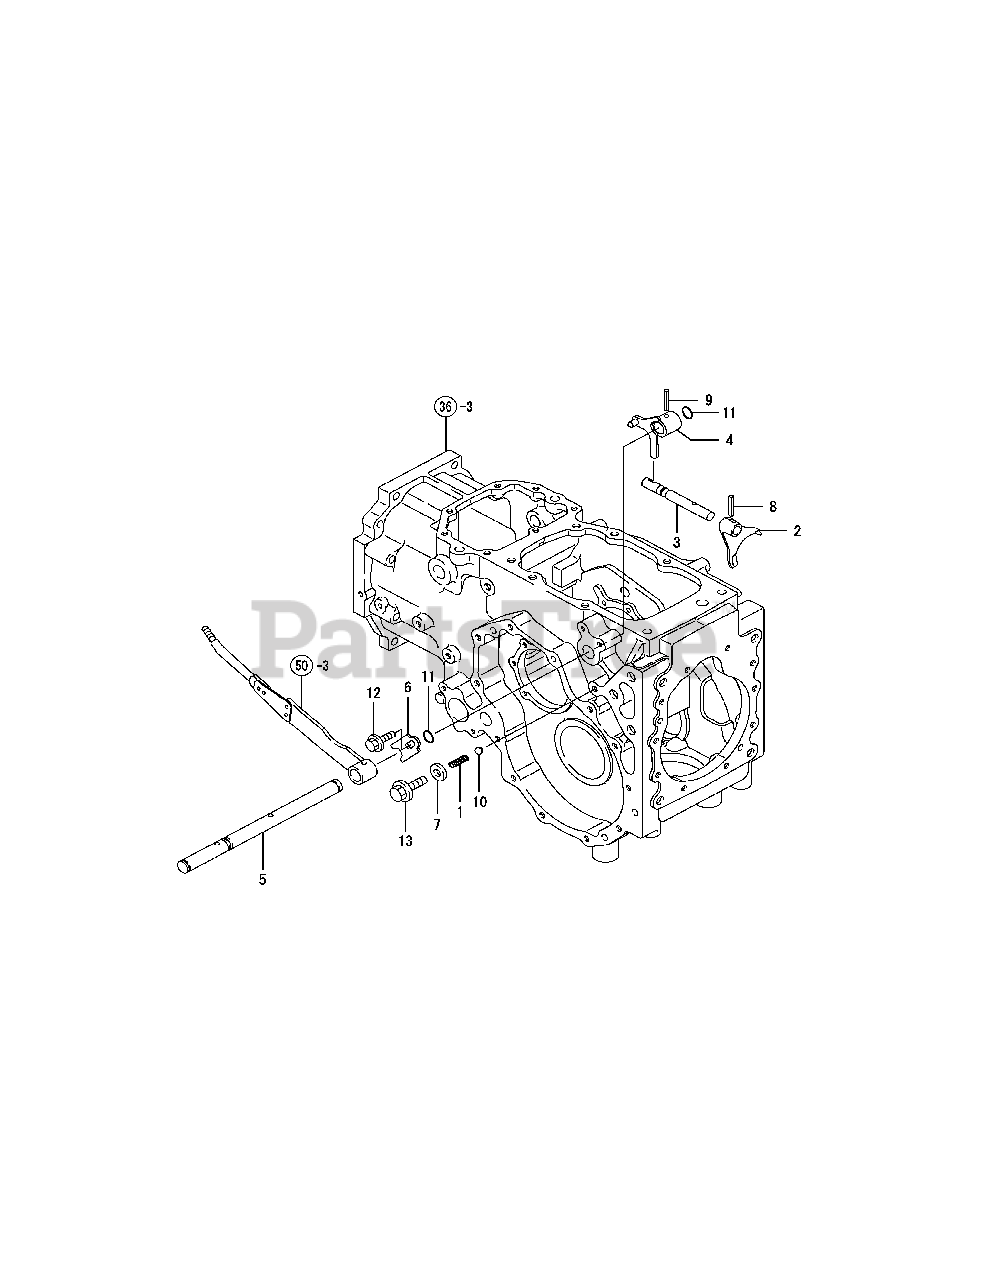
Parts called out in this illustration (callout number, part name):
2	FORK, SHIFTER PTO
3	SHAFT, FORK PTO
4	ARM, SHIFT PTO
7	SEAL WASHER 10(BOLT)
8	SPRING PIN 6X32
9	SPRING PIN 6X32
10	BALL 5/16, STEEL
11	O-RING 1A P-15.0
12	BOLT M 8X 16 PLATED
13	BOLT M10X 25 PLATED
